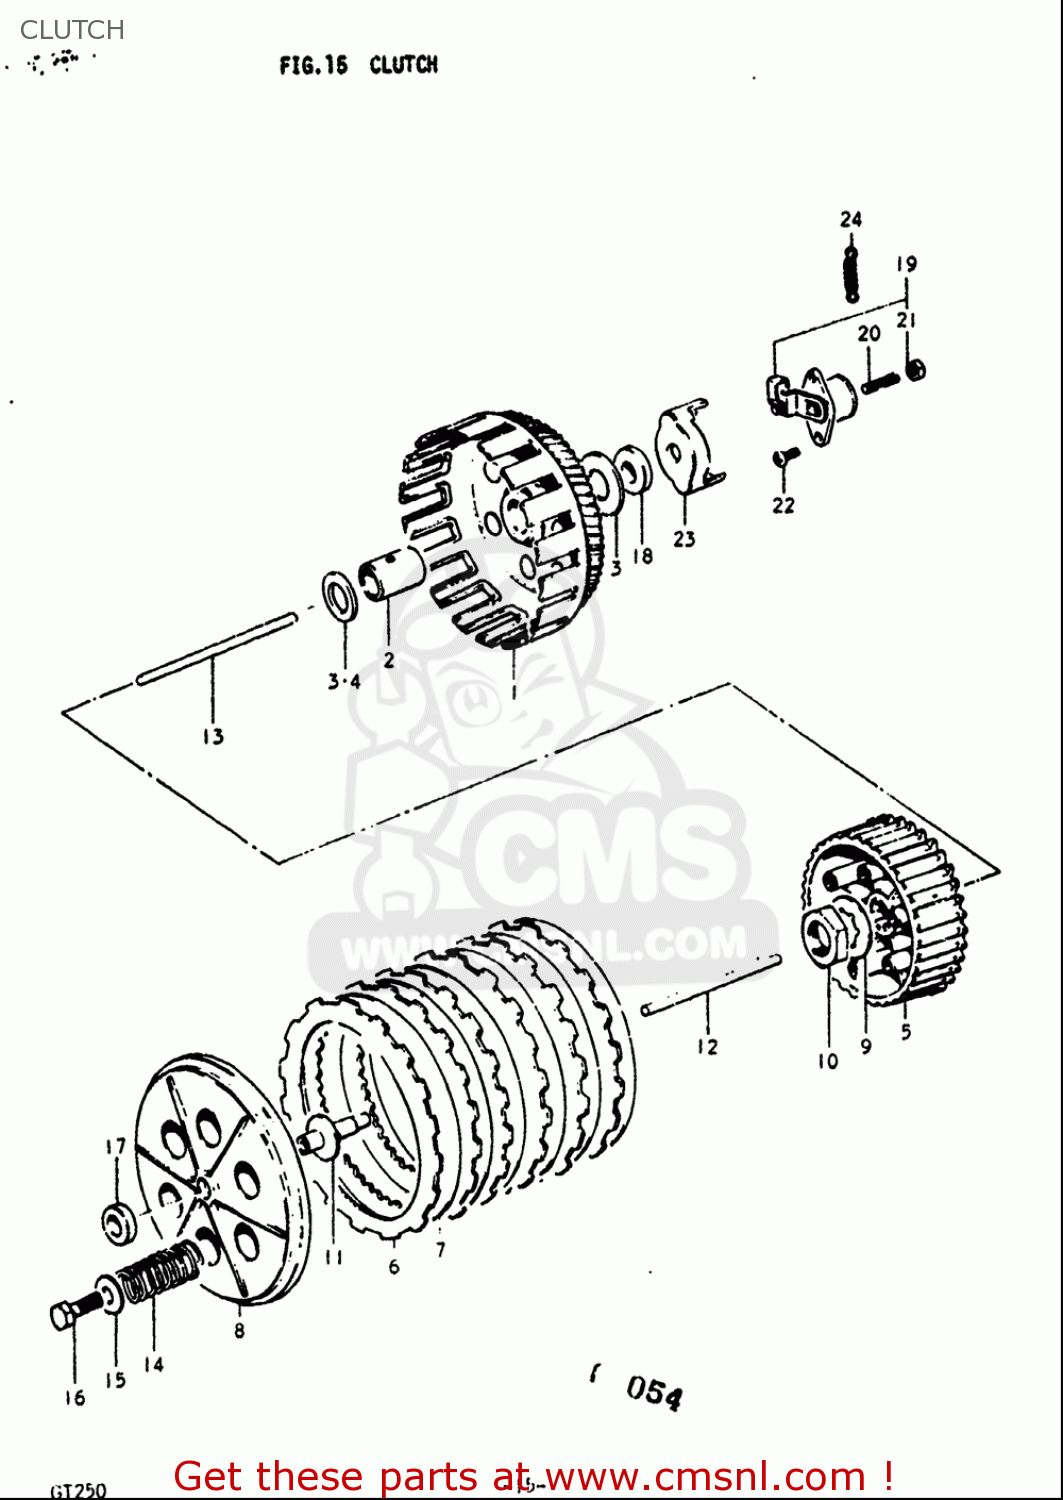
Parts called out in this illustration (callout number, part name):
2	SPACER,PRIMARY DRIVEN GEAR
3	WASHER
6	PLATE,CLUTCH DRIVE(T:3.5) (NAS)
7	PLATE,CLUTCH DRIVEN(T:2.0) (NAS)
9	WASHER,LOCK
10	NUT
12	ROD,CLUTCH PUSH
13	ROD, CLUTCH PUSH B
14	SPRING
15	WASHER(6.5X20X1.6)
16	BOLT
17	SEAL,OIL (10X17X5)
18	SEAL,OIL (6X30X5)
20	SCREW(6X25)
21	NUT
22	SCREW
24	SPRING
